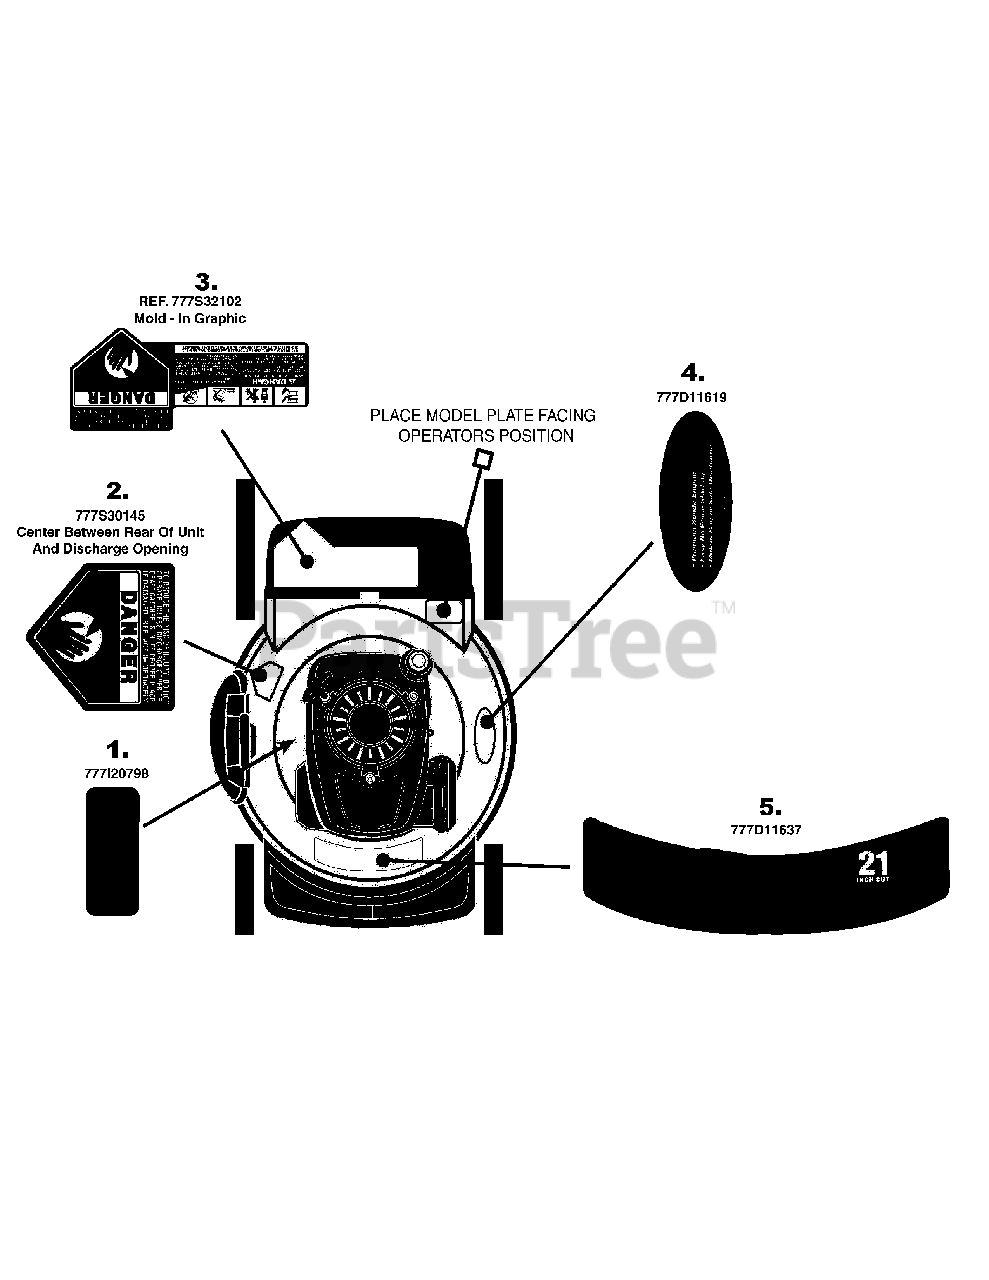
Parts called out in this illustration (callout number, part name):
1	LABEL-SHROUD
2	LABEL
3	LABEL
4	LABEL-MOWER SD DECK YARD MAN
5	LABEL-MOWER DECK SWIRL YARD MAN
